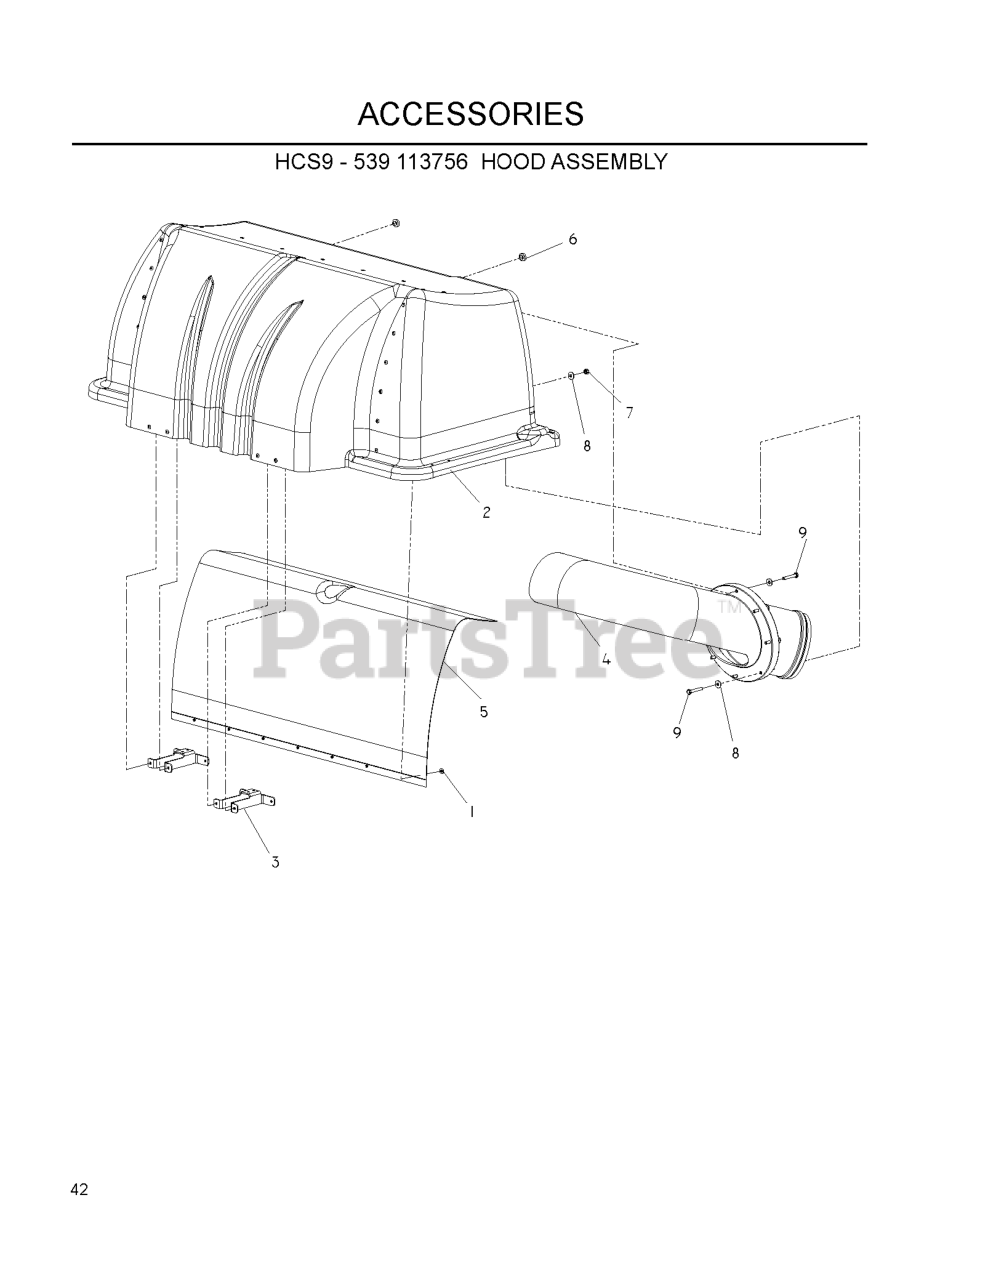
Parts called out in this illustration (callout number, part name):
1	WASHER #10
3	SUPPORT, DRAW LATCH
5	MESH, POLY DIAMOND
6	GROMMET, BUMPER
7	NUT.1/4-20.HEX.NYLOC.ZD
8	WASHER 1/4 FLAT
9	BOLT 1/4C X 1 3/4
